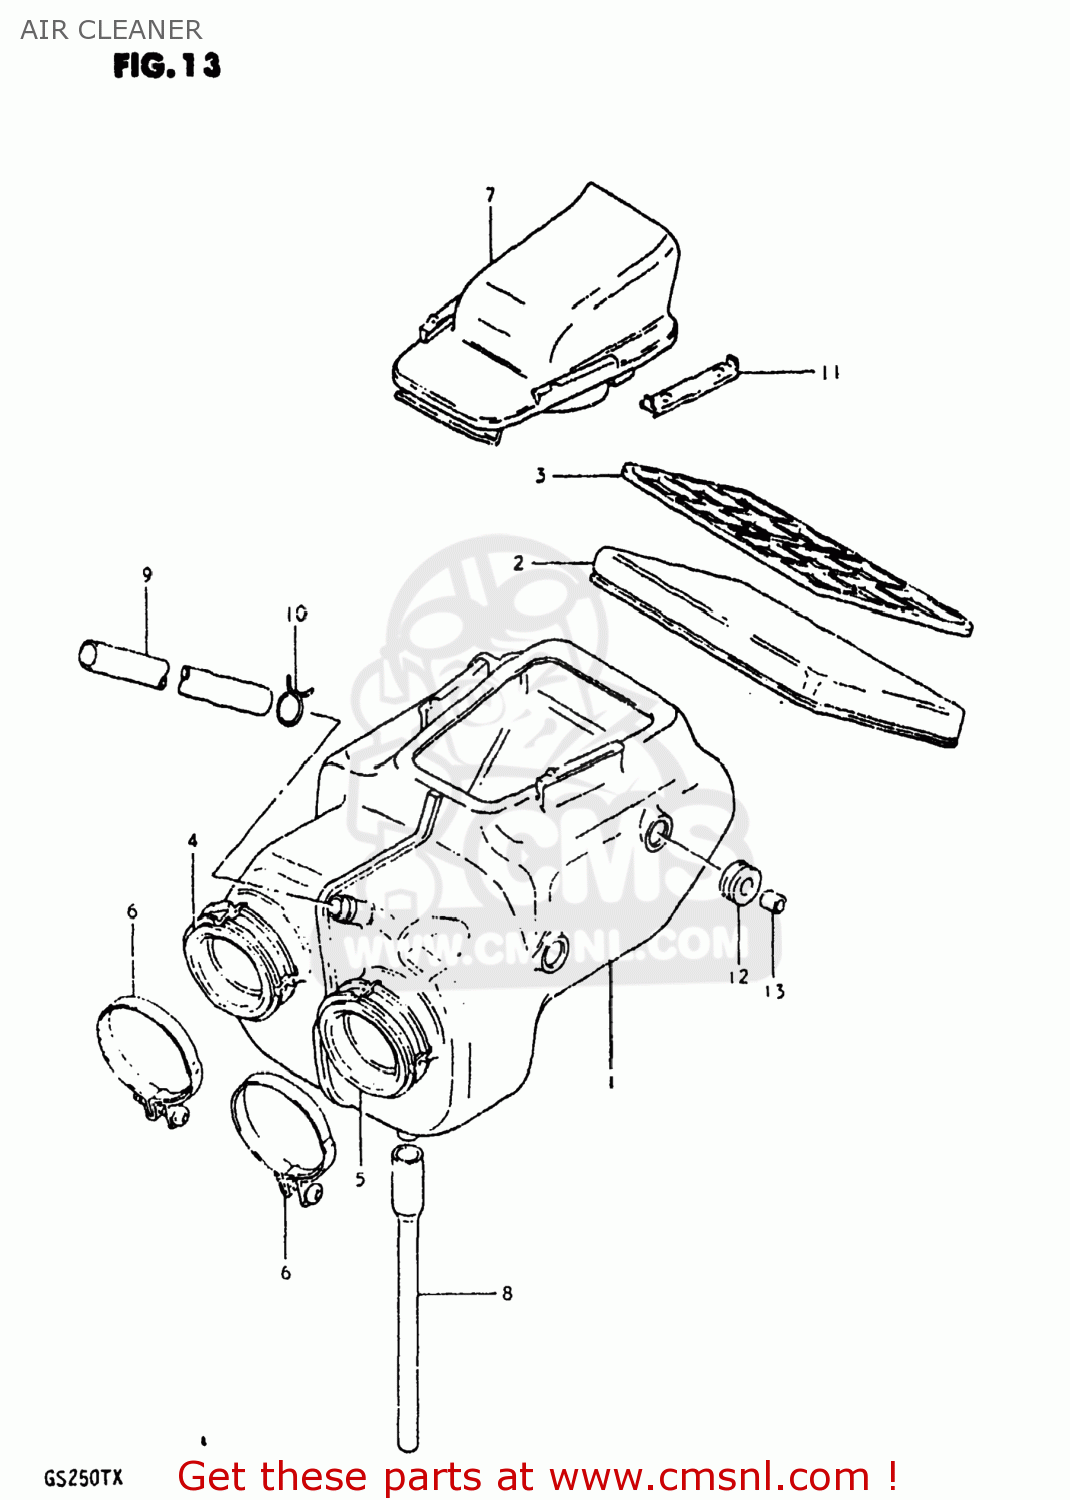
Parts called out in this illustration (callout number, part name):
1	CLEANER ASSEMBLY,AIR
2	FILTER
3	HOLDER NO.2
4	OUTLET,R
5	OUTLET,L
6	CLAMP
7	CAP
8	DRAIN TUBE
9	TUBE,BREATHER
10	CLAMP
11	SLIDER
12	CUSHION
13	SPACER(6.1X9X7.5)
